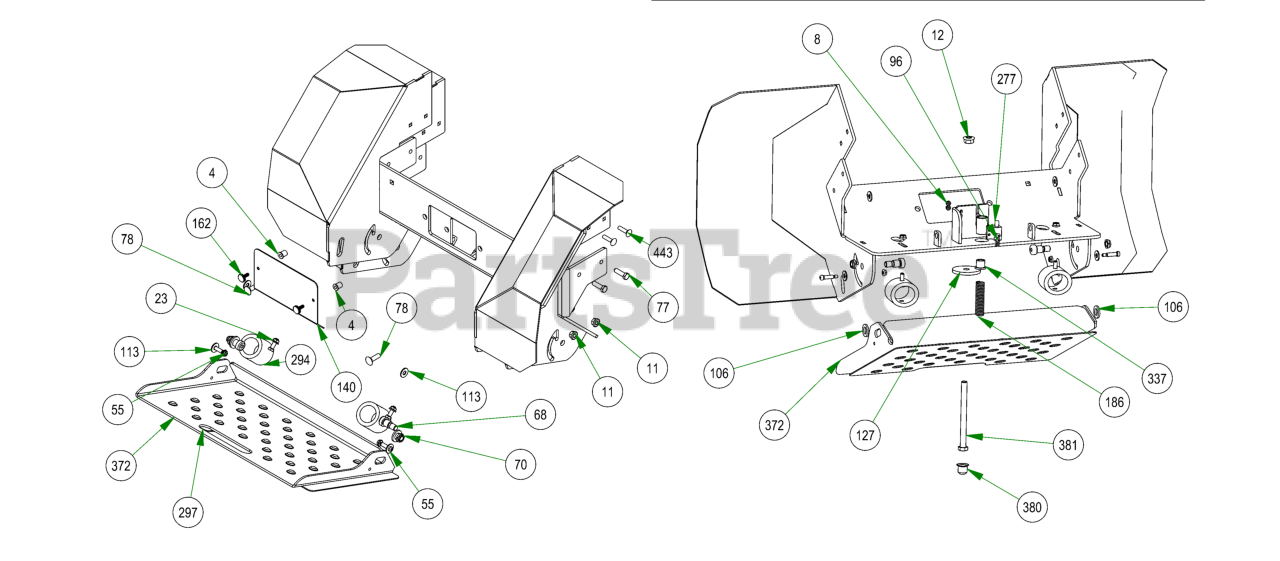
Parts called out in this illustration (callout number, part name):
4	3326 Wellnut (1/4-20 x 5/18")
8	10-24 NYLON INSERT LOCKNUT ZINC
11	3/8-16 NYLON INSERT FLANGE LOCKNUT (GR.F) ZINC
12	1/2-13 HEX SERRATED FLANGE NUT HARD/ZINC
19	5/16-18 NYLON INSERT FLANGE LOCKNUT ZINC
21	1/4-20 NYLON INSERT LOCKNUT ZINC
22	1/4-20 HEX SERRATED FLANGE NUT HARD/ZINC
23	5/16-18 HEX SERRATED FLANGE NUT HARD/ZINC
55	Steel Shoulder Screw 1/4"-20 x 7/8" Diameter 5/16"
64	5/16-18 X 1 HEX CAP SCREW (GR.5) ZINC
67	3/8-16 X 2 HEX CAP SCREW (GR.5) ZINC
68	5/8 X 5/8 SOCKET SHOULDER BOLT ZINC YELLOW
70	1/2-13 NYLON INSERT JAM LOCKNUT ZINC
77	3/8-16 X 1-1/4 HEX CAP SCREW (GR.5) ZINC
78	3/8-16 X 1-1/4 CARRIAGE BOLT ZINC
95	1/4-20 X 3/4 HEX CAP SCREW (GR.5) ZINC
96	10-24 X 3/4 BUTTON SOCKET CAP SCREW 18-8 STAINLESS STEEL
106	.635 ID X 1.120 OD X .140 THICK FLAT WASHER NYLON
109	.360 ID X .983 OD X .120 THICK FLAT WASHER NYLON
113	5/16 USS FLAT WASHER (7/8 OD) ZINC
114	5/16 SPLIT LOCKWASHER ZINC
127	MZ Deck Idler Spacer
140	2019 Stand On Access Panel Plate Black Part
149	2020 36" Revolt Platform Plate-Powdercoated
186	Rider Presence Spring 9657K145
266	2020 36" Stand On Frame
271	2022 Stand-On Revolt Platform Pad
273	2022 36" Revolt Seat Pad
277	safety Switch
294	GBR-647 Miner Elastomer
297	Grip Tape for 026-0062-00
298	Grip Tape for 026-0158-00
309	2022 Powered By Vanguard Decal
310	2022 Powered By Kawasaki Decal
319	810cc Revolt EFI Fender Decal
320	852cc Revolt EFI Fender Decal
337	Nylon 6 6 Sleeve Washer
371	2023 Platform Support 61 weldment
371.1	rider presence tab
371.2	Rider presence tab2
371.3	2019 Stand-on Transaxle bolt Tab
371.4	Fender Left_61
371.5	Fender Right_61
371.7	2023 Platform Sides LH
371.8	2023 Platform Sides_RH
371.9	.750 ID x 1 OD x 1.5 long spacer
372	2023 Platform_2
375	2023 Platform Support 54/48
375.1	rider presence tab
375.2	Rider presence tab2
375.3	2019 Stand-on Transaxle bolt Tab
375.4	2023 Platform plate
375.5	2023 Platform Sides LH
375.6	2023 Platform Sides_RH
375.7	.750 ID x 1 OD x 1.5 long spacer
375.8	Fender Left Plate
375.9	Fender Right Plate
376	2023 36 Platform Support
376.1	rider presence tab
376.2	Rider presence tab2
376.3	2019 Stand-on Transaxle bolt Tab
376.4	2023 36 Platform plate
376.5	2020 36 Fender_left
376.6	2020 36 Fender_right
376.7	2023 36 Platform Sides LH
376.8	2023 36 Platform Side_RH
376.9	.750 ID x 1 OD x 1.5 long spacer
377	2023 Stand on Pad Plate
378	Adjustable handles ERX.30 B-10-24-C1
380	Hex Nut Cap
381	1/2-13 X 6 HEX CAP SCREW (GR.5) ZINC
409	2023 36-SD Stand on Pad Plate
443	5/16-18 X 1-1/4 CARRIAGE BOLT ZINC
